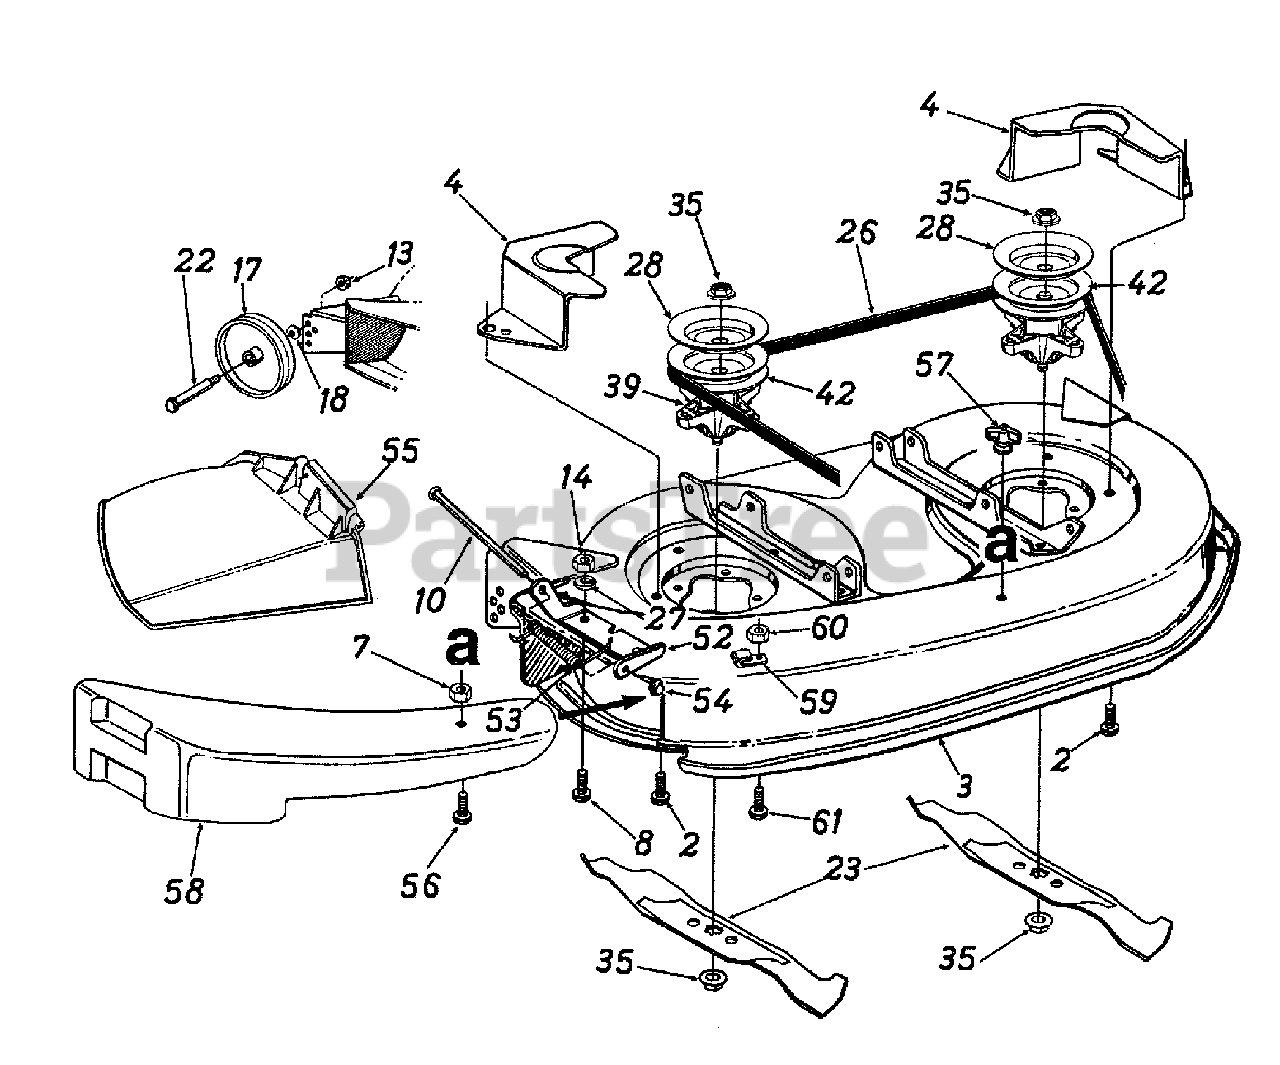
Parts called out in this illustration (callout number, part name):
2	Hex Wash. Hd. TT-Tap Scr. 5/16-18 x .75" Lg.
7	Hex L-Nut 1/4-20 Thd.
8	Hex Bolt 1/4-20 x .62"
10	Hinge Pin
13	Hex Top L-Nut 3/8-16 Thd.
14	Hex Nut 1/4-20 Thd. (Gr. 5)
17	Deck Wheel-5"
18	Bell-Wash. .40" I.D. x .88" O.D.
22	Shld. Bolt .498" Dia. x 1.53"
23	3 in 1 Blade
26	V-Belt
27	Bell-Wash. 1/4" I.D.
28	Brake Disc
35	Hex Flange Nut 5/8-18 Thd.
39	Blade Spindle Ass'y. Comp.
42	5.75" Dia. Pulley
52	Hinge Mtg. Brkt.
53	Torsion Spring
54	Push Nut
55	Chute Ass'y. Comp.
56	Hex Bolt 1/4-20 x 1" Lg.
57	Wing Nut 1/4-20 Thd.
58	Mulching Plug
59	Retainer Hook Brkt.
60	Hex Sems Nut 1/4-20 Thd.
61	Hex Bolt 1/4-20 x .62" Lg.
